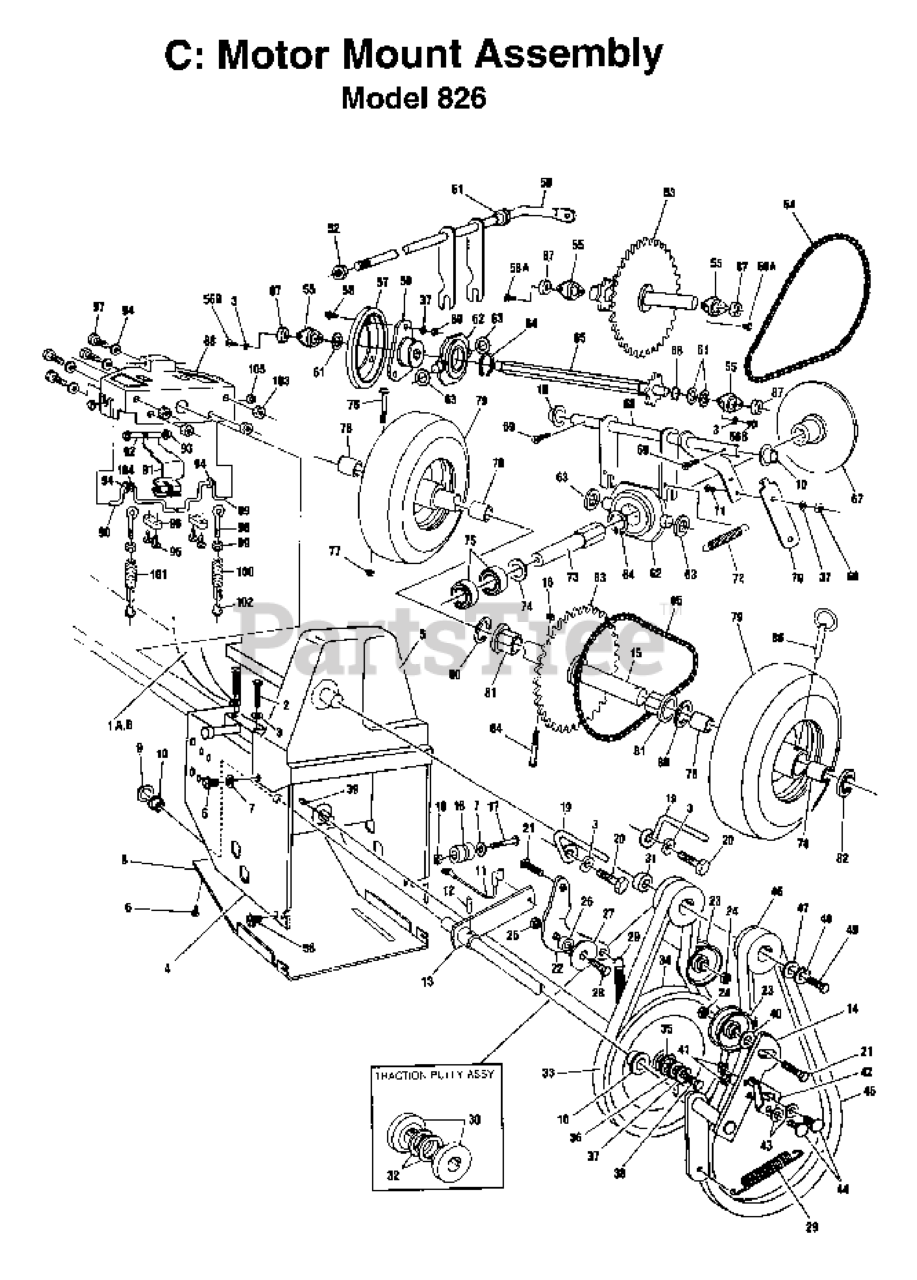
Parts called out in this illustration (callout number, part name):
2	HEX BOLT
3	WASHER.LOCK.HVY.HLCL.SPR.5/16
17	BOLT HEX FIN 1/4-20X1 3/4
18	NUT.CROWNLOCK.1/4
21	BOLT
25	LOCKNUT
28	BOLT.FIN.HEX.5/16-18X3/4
37	LOCKWASHER
38	BOLT
41	NUT.CROWNLOCK.1/4
49	BOLT.HEX.001X20.37-24X1.ZINC
57	FICTION WHEEL
60	NUT
65	SHAFT/SPROCKET ASSY
69	PIN COTTER
71	BOLT
77	NUT.CROWNLOCK.1/4
85	CHAIN, ROLLER #42X40 PITCH
